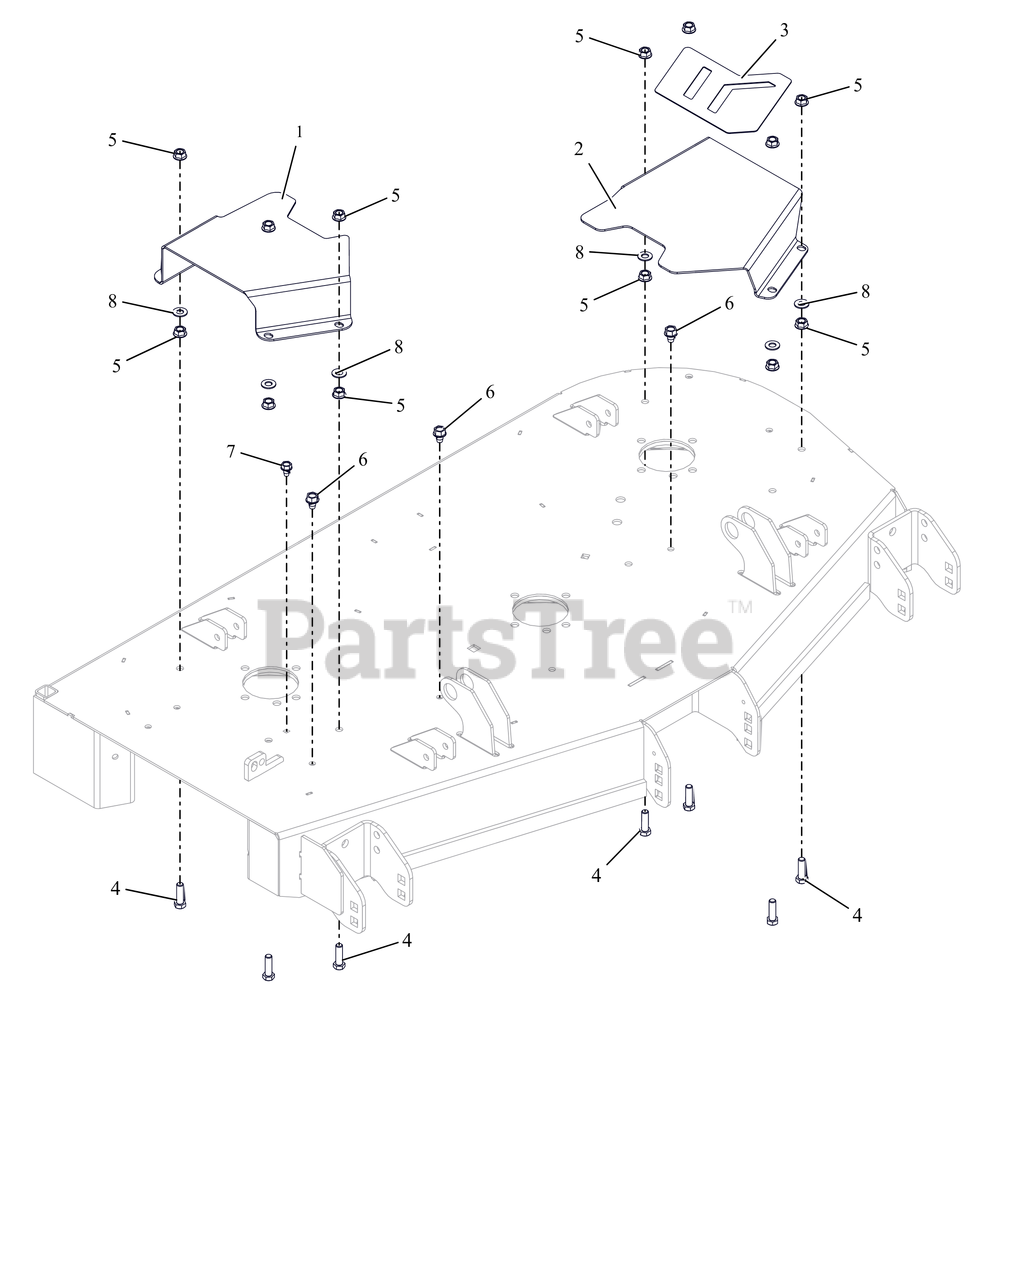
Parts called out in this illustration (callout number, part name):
1	COVER, BELT 48" RIGHT
2	COVER, BELT 48" LEFT
3	GRIP TAPE 48 BELT COVER
4	@BLT-HEX .38-16X1.25 GR5 YWZC
5	@NUT-SPNLK-FLG .375-16 YWZC
6	@SCR-TAP .38-16X.50 HWH TR YWZ
7	@SCR-TAP .31-18X.50 HWH TR YWZ
8	@WSHR-FL-STL.406X.812X.065 YWZ
